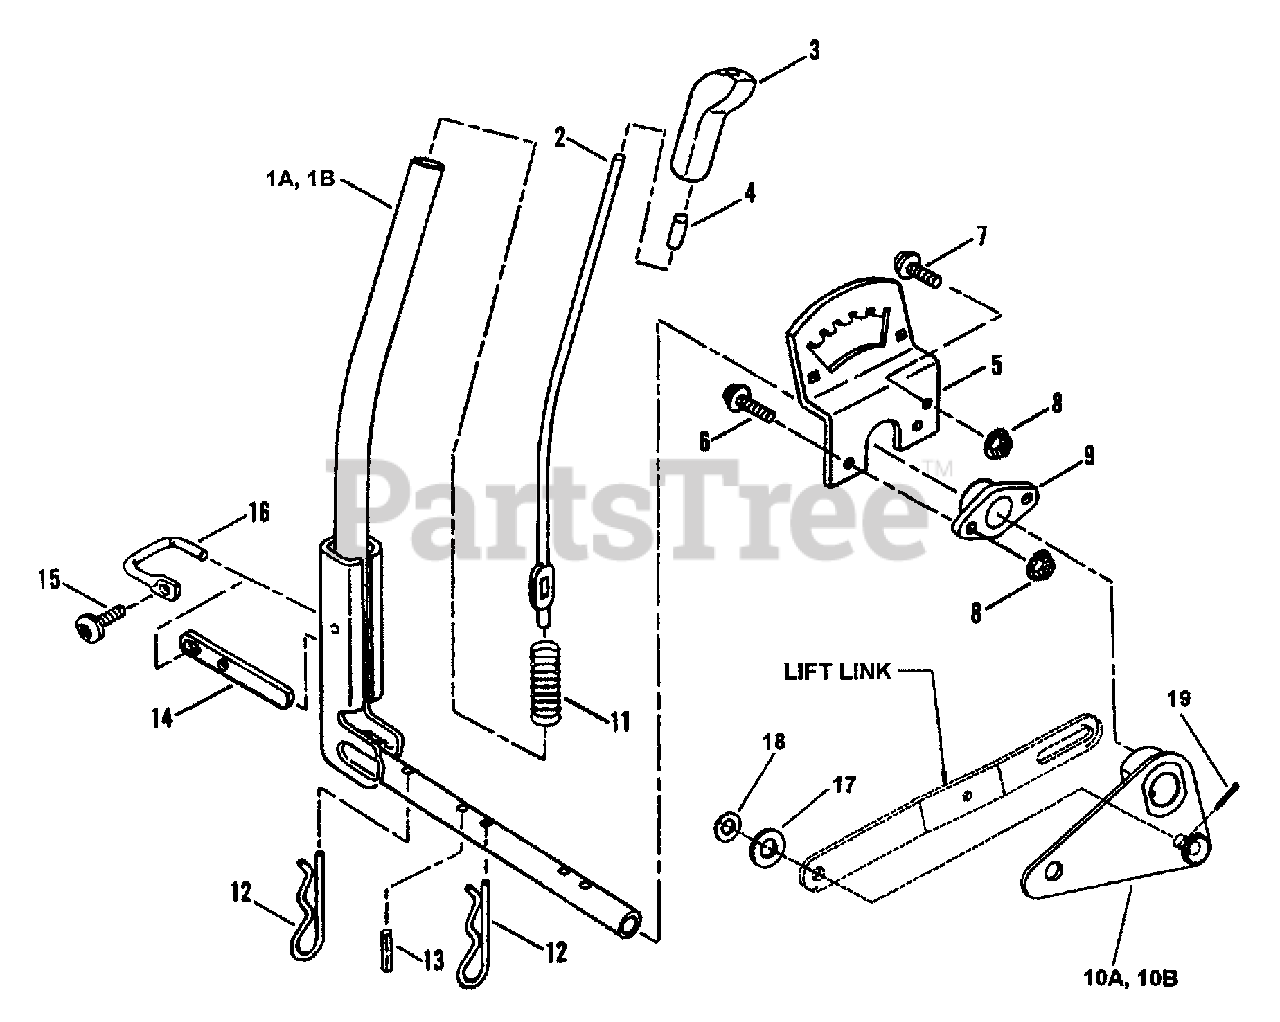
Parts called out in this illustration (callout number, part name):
1A	LEVER, Implement Lift
2	ROD, Lift Lever
3	KNOB, Lift Lever
4	CAP, Lift Lever Rod
5	QUADRANT, Lift Lever
6	SCREW, 5/16-18 x 7/8" Truss Head (Torx)
7	SCREW, 5/16-18 x 5/8" Truss Head (Torx)
8	NUT, 5/16-18 Hex Flange Lock, Grade 5
9	PIVOT, Lift Lever
10A	BELLCRANK, Lift Lever
10B	BELLCRANK, Lift Lever
11	SPRING, Latch Detent
12	PIN, Hair, 5/32 x 2-5/8"
13	PIN, Dowel, 1/4 x 1-1/8"
14	DETENT, Latch
15	SCREW, 1/4-20 x 5/8" Truss Head (Torx)
16	LATCH, Pivot
17	WASHER, 1/2" Flat
18	WASHER, 3/8" Flat
19	PIN, 3/32 x 3/4" Cotter
